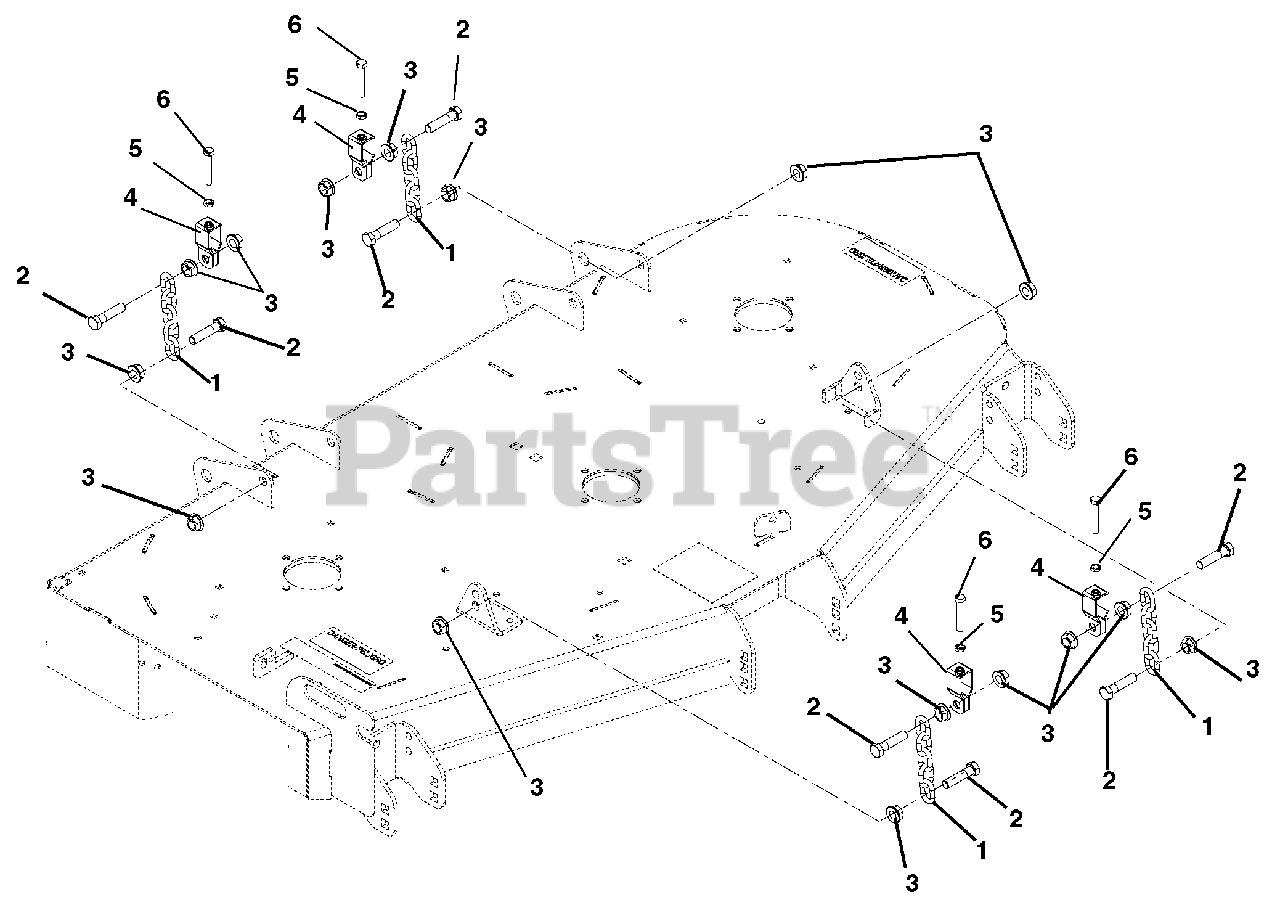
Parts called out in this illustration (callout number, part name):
1	Chain, Link
2	Bolt, Hex M12-1.75 x 50 Class 8.8
3	Nut, Spin Lock-Flange M12-1.75
4	Bracket, Deck Leveling
5	Nut, Jam .312-18
6	Bolt, Hex .312-18 x 2.00 FTH Grade 5
